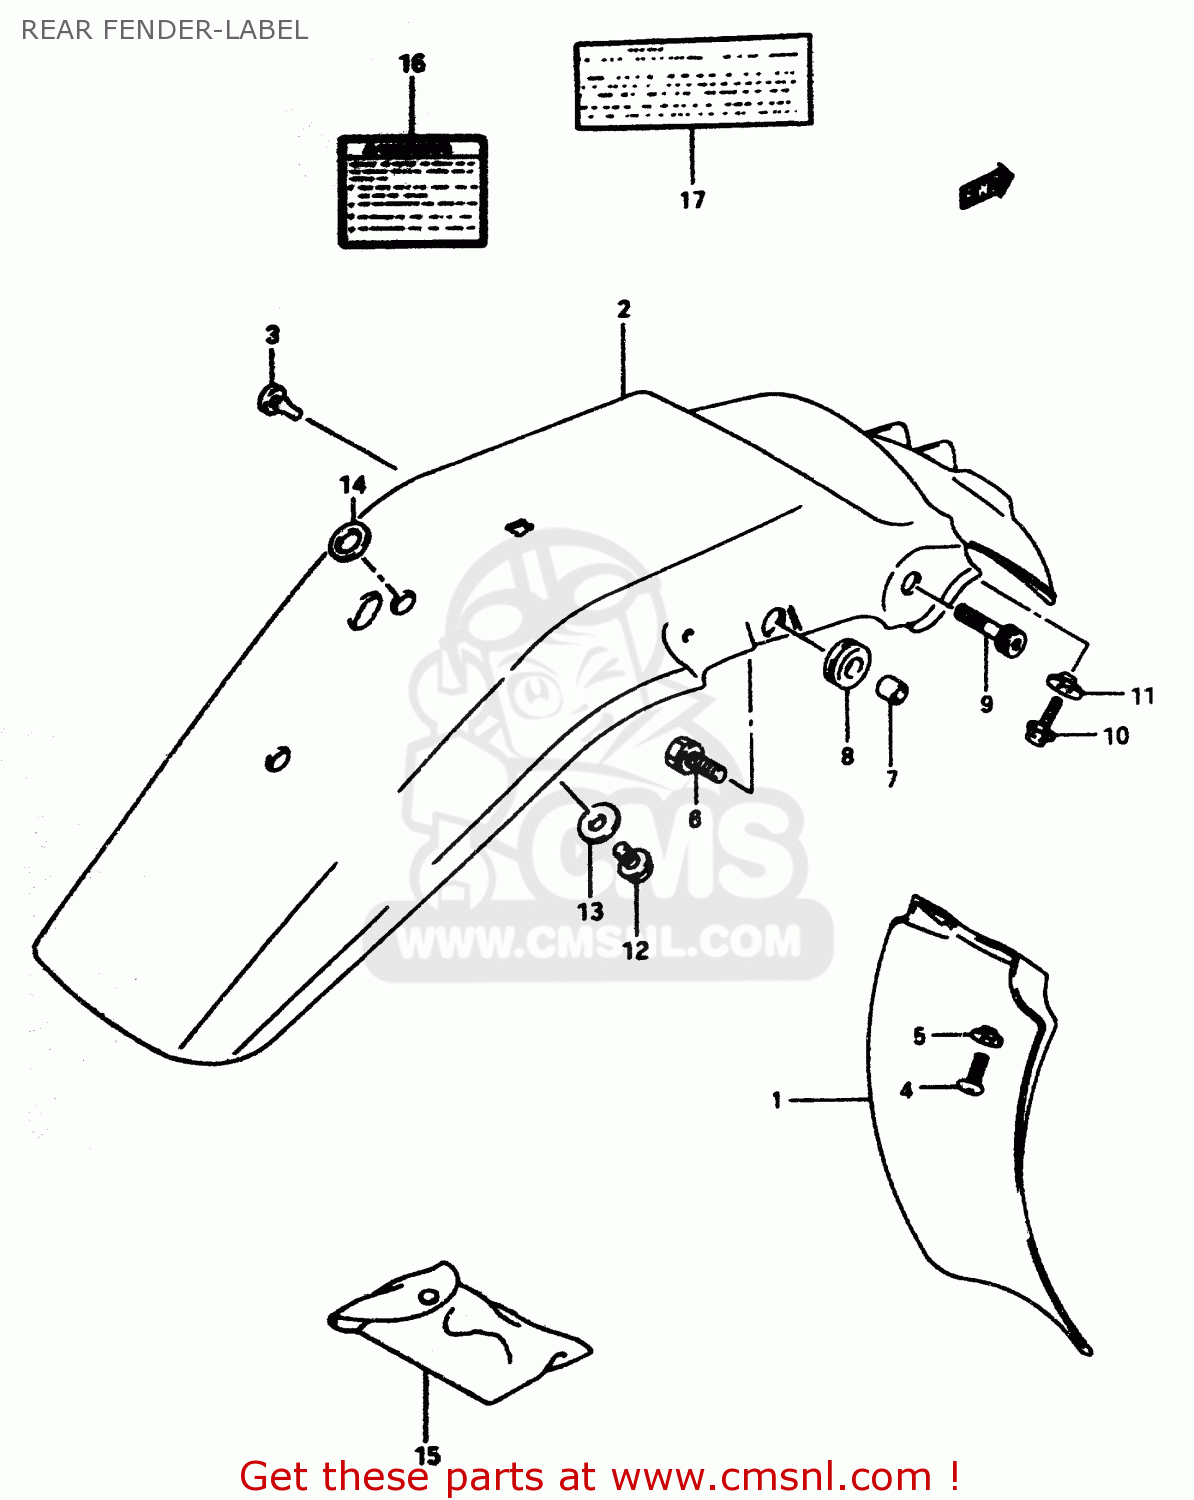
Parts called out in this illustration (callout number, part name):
1	BODY,RR FENDER FR
2	BODY,RR FENDER RR
3	CUSHION,RR FENDER SIDE
4	SCREW 6X12
5	WASHER
6	BOLT
7	SPACER(8.5X12X7)
8	CUSHION
9	BOLT(8X30)
10	BOLT
11	WASHER
12	BOLT, UPPER
13	WASHER
14	WASHER(14.2X26X1.2)
15	TOOL ASSY
16	LABEL,WARNING SAFETY
17	LABEL (MANUAL NOTICE)
18	MANUAL,OWNER'S
